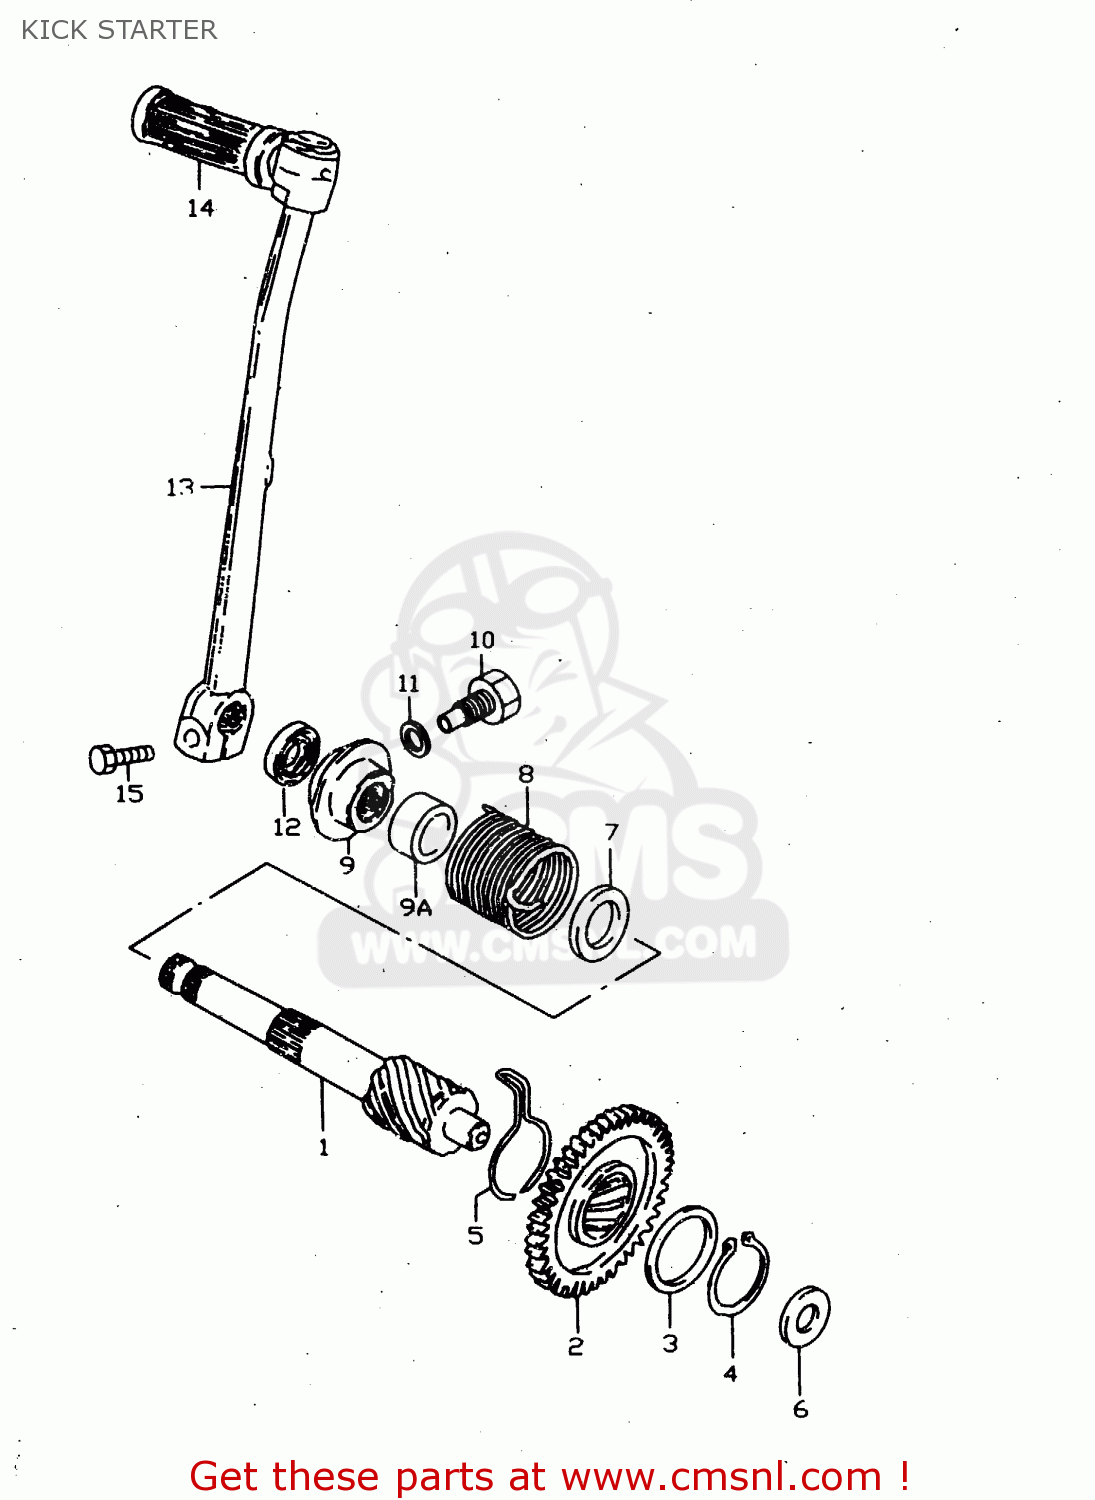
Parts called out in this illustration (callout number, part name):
1	SHAFT,KICK STARTER
2	GEAR,KICK STARTER DRIVE
3	WASHER
4	CIRCLIP
5	RETAINER,SNAP
6	WASHER
7	WASHER(16X30X1)
8	SPRING
9	LIFTER,KICK STARTER
9A	GUIDE,KICK RETURN SPRING
10	BOLT(10X17)
11	GASKET(10X14X3.6) (NAS)
12	SEAL,OIL(14X24X6)
13	LEVER ASSY,KICK STARTER
14	RUBBER,KICK STARTER PEDAL
15	BOLT
